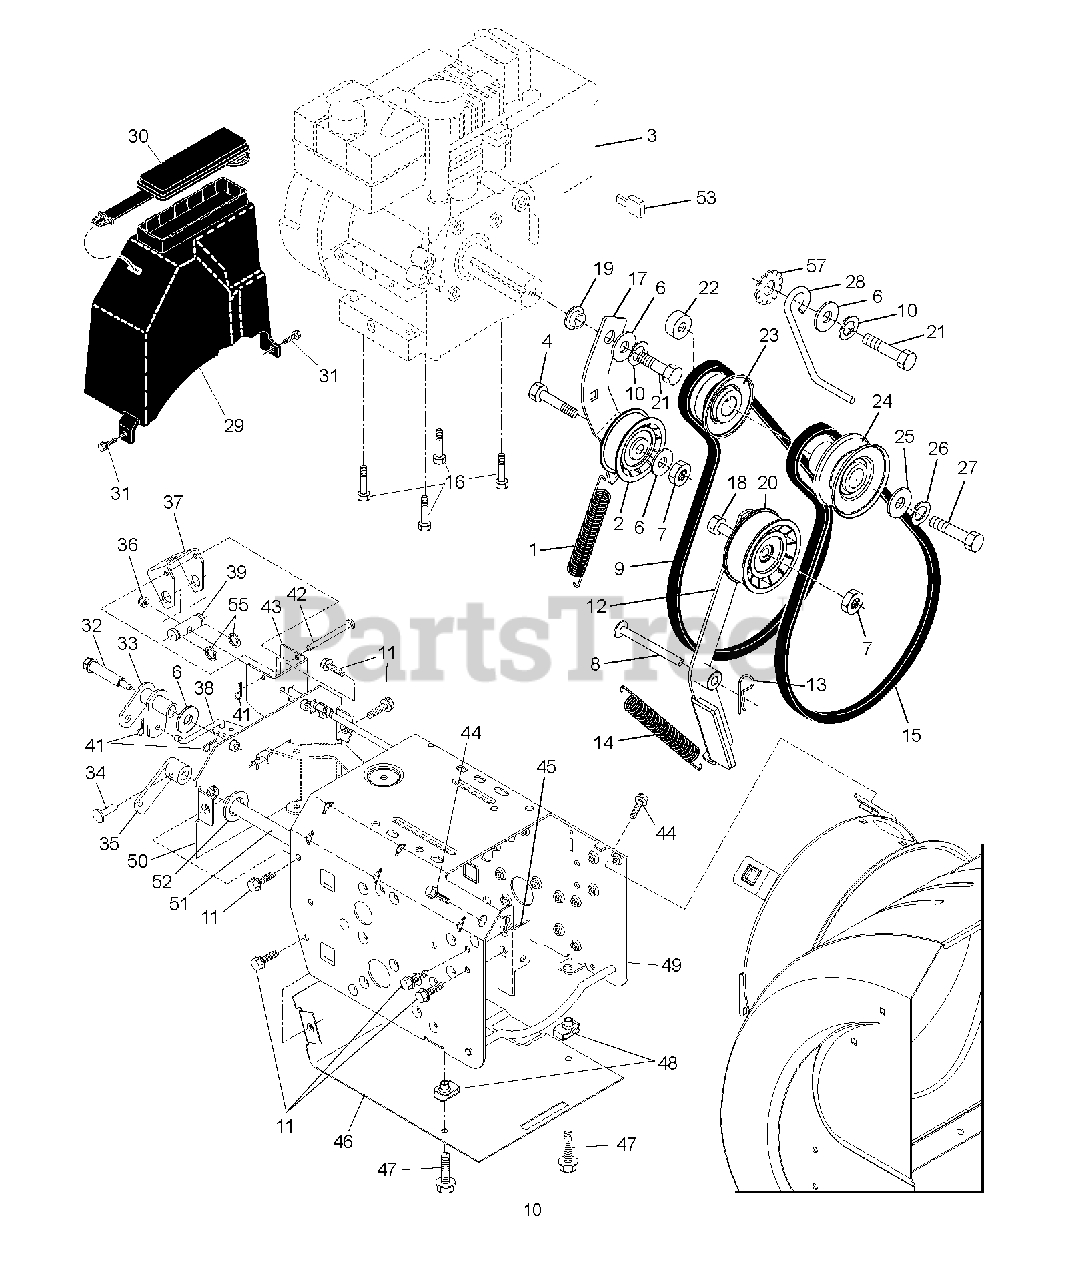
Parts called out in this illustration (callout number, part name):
1	RP SPRING, TRACTION IDLER
2	PULLEY.W/SPACER.2.25
4	BOLT.5/16-18X1-1/4 FULL.THREAD
6	STEEL WASHER
7	LOCKNUT 5/16-18
8	PIN, IDLER PIVOT
9	V-BELT, TRACTION DRIVE
10	LOCKWASHER
11	SCREW, HEX HEAD 5/16-18 X 1/2
12	ARM ASSEMBLY, IMPELLER IDLER
13	RETAINER CLIP PM
14	SPRING, BRAKE
15	V-BELT, IMPELLER DRIVE
16	BOLT 3/8-16X1-1/8
17	IDLER ARM
18	HEX BOLT
19	BUSHING, IDLER PIVOT
20	PULLEY.W/SPACER.2.75
22	SPACER, ENGINE PULLEY
23	PULLEY, ENGINE TRACTION DRIVE
24	PULLEY, ENGINE IMPELLER DRIVE
25	WASHER, FLAT 3/8
26	LOCKWASHER
27	SCREW, HEX HD 3/8-24 X 1-3/8
28	GUIDE BELT
29	COVER.ASM.BELT/STORAGE
30	COVER.STORAGE.SNOW
31	SCREW, HEX HEAD 1/4-20
32	BOLT, SHOULDER 5/16-18
33	BELLCRANK SHIFTER
34	CLEVIS PIN
35	ARM, AUGER CONTROL
36	NUT.71038.31-18.HEX.NYLOCK
37	BRACKET, PIVOT
38	LINK, SPEED CONTROL
39	TRUNNION, TRACTION
41	RETAINER CLIP
42	PIN, PIVOT BRACKET
44	SCREW 3/8-16X1
45	BRACKET, IDLER PIVOT
46	PAN, FRAME BOTTOM
47	SCREW, HEX HD 5/16 -18 X 3/4
48	NUT, SPEED 5/16-18
51	SHAFT, AUGER CONTROL
52	THRUST WASHER
53	KEY, SAFETY IGNITION (BRIGGS)
57	WASHER EXT TOOTH LOCK 5/16
